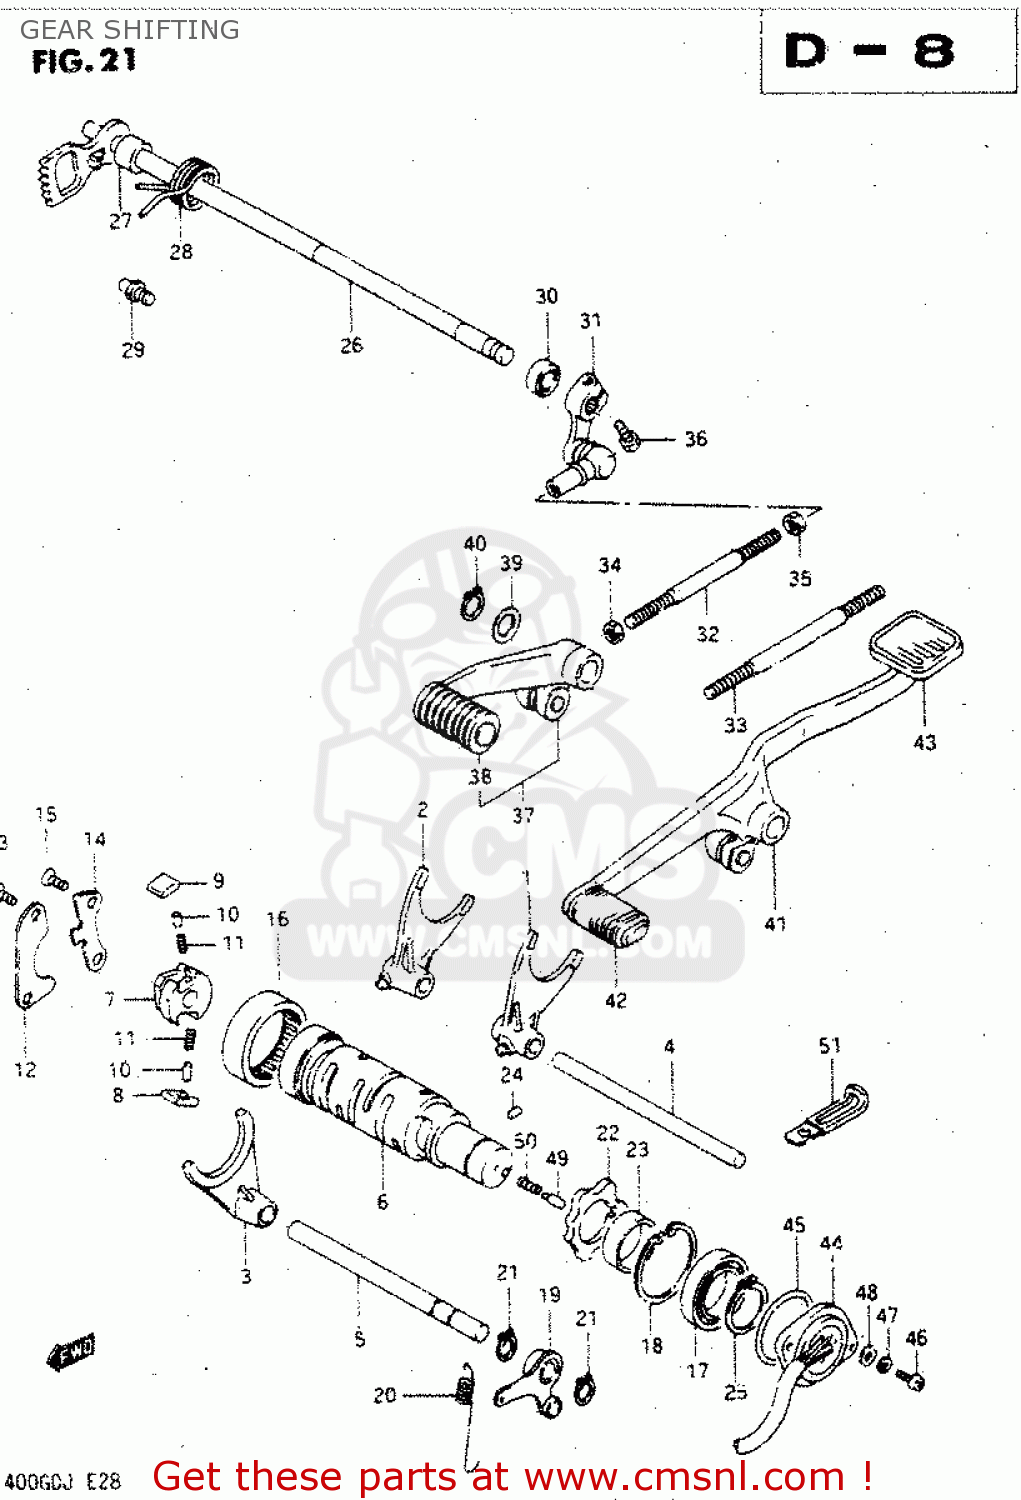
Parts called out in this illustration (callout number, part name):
1	FORK,GEAR SHIFT NO.1
2	FORK,GEAR SHIFT NO.2
3	FORK,GEAR SHIFT NO.3
4	SHAFT,GEAR SHIFT FORK
5	SHAFT,GEAR SHIFT FORK
6	CAM COMP,GEAR SHIFT
7	GEAR,GEARSHIFT CAM DRIVE
8	PAWL,GEAR SHIFT NO.1
9	PAWL,GEAR SHIFT NO.2
10	PIN(5X8)
11	SPRING
12	LIFTER, PAWL
13	SCREW
14	GUIDE,GEAR SHIFTING CABLE
15	SCREW
16	BEARING(43X49X12)
17	BALL BEARING
18	CIRCLIP,42MM
19	STOPPER,GEAR SHIFT CAM
20	SPRING
21	CIRCLIP
22	PLATE,GEAR SHIFT CAM STOPPER
23	SPACER
24	PIN 4X6
25	CIRCLIP,25MM
26	SHAFT,GEAR SHIFTING
27	SPACER(12X20X15.3)
28	SPRING
29	STOPPER,GEAR SHIFT CAM
30	OIL SEAL
31	ARM,GEAR SHIFT
32	ROD,GEAR SHIFT LINK
33	ROD,GEAR SHIFT LINK NO.2
34	NUT
35	NUT 6MM
36	BOLT
37	LEVER ASSEMBLY,GEAR SHIFTING
38	RUBBER,GEAR SHIFT PEDAL
39	WASHER(12.5X20X1)
40	CIRCLIP
41	LEVER ASSEMBLY,GEAR SHIFTING
42	RUBBER,PEDAL
43	RUBBER, PEDAL REAR
44	BASE ASSEMBLY,GEAR SHIFT TERMINAL
45	O RING(D:2.4,ID:36.5)
46	SCREW(5X14)
47	LOCK WASHER
48	WASHER
49	PIN(5X15.5)
50	SPRING
51	CLAMP L:35
